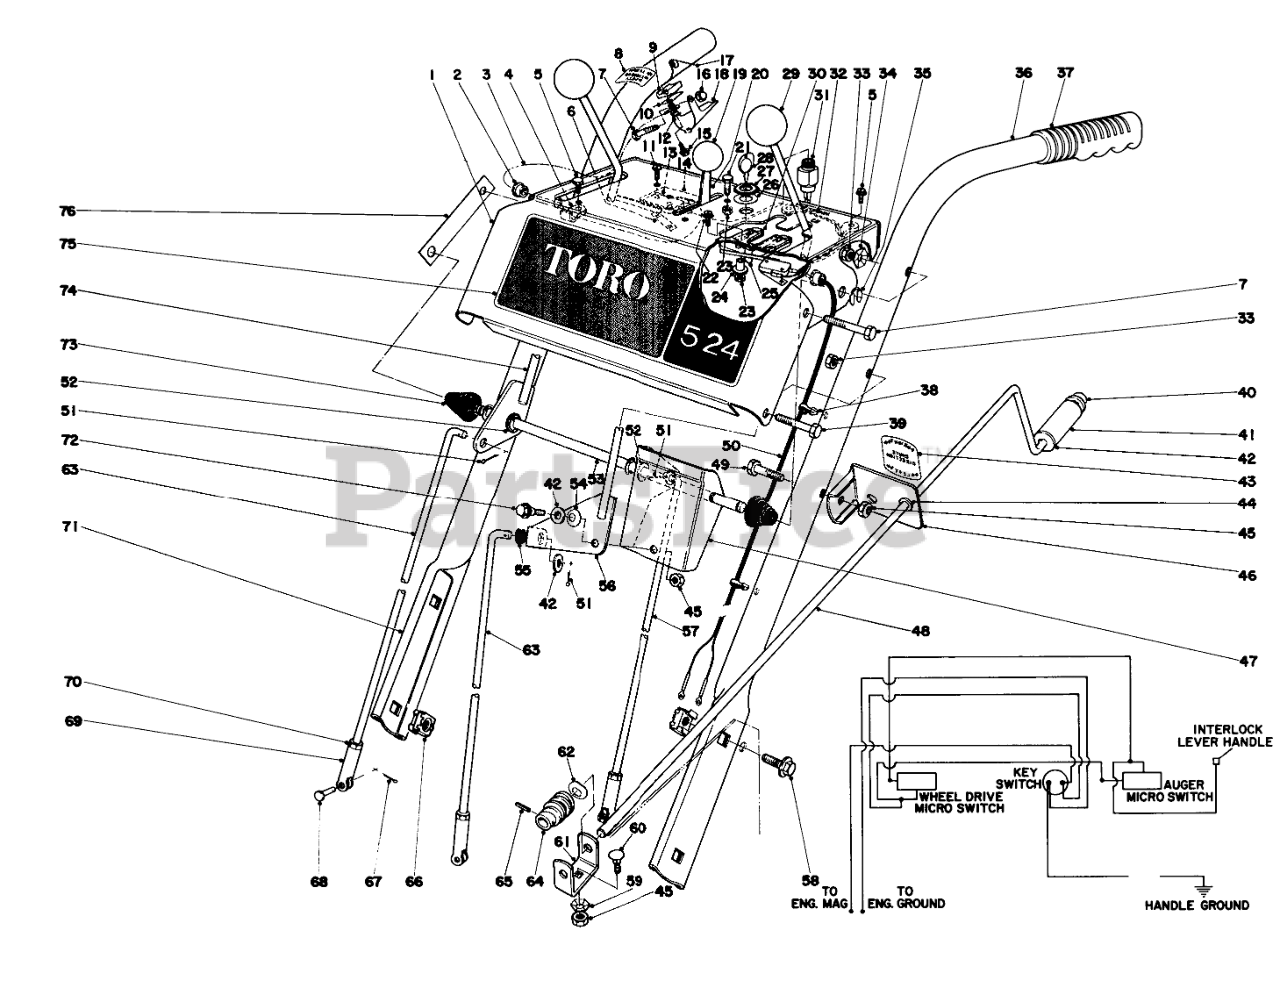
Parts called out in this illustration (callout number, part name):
1	Escutcheon
2	Snap Bushing
3	WIRE ASM
4	PLASTIC CLIP
5	SCREW-HWHTF
6	NUT-SPEED
7	SCREW-HH
8	Decal Safety Interlock
9	Insulator
10	INTERLOCK CONTACT
11	SCREW-HEAD, PAN
12	WASHER INSULATOR
13	MICRO SWITCH
14	SWITCH MTG PAD
15	Screw
16	NUT-CAP
17	INTERLOCK SPRING
18	Safety Lever
19	CONTROL KNOB
20	Throttle Control
21	HEX HEAD SEMS 10-24X1/2
22	SCREW-SRH
23	Nut
24	INTERLOCK SPACER
25	INTERLOCK SPRING
26	WASHER-TOOTH, INTERNAL
27	NUT-HH
28	Ket (set of 2)
30	Slide Interlock
31	Switch
32	Decal Instruction
33	NUT-LOCK, CONE
34	Washer
35	Klip Ring
36	LEFT HANDLE
37	Grip Handle
38	Mount-Wire
39	SCREW-HH
40	RETAINER-PUSH ON
41	CHUTE CONTROL GRIP
42	WASHER-FLAT
43	Decal Chute Direction
44	Bushing
45	NUT-LOCK, CONE
46	Chute Control Rod Mounting Bracket (Incl. Ref. 43-44)
47	SHIFT BRACKET
48	CHUTE CONTROL ROD
49	SCREW-HH
50	Wire Harness
51	PIN-COTTER
52	WASHER-FLAT
53	PIVOT ROD
54	7/16 SPRING WASHER
55	GROMMET-RUBBER
56	SHIFT LEVER WA
57	TRACTION CONTROL ROD
58	SCREW-HHF
59	WASHER-LOCK
60	BOLT-CARR
61	WORM BRACKET
62	WASHER-SPRING
63	SPEED SELECTOR ROD
64	GEAR-WORM, CHUTE
65	PIN-SPRING
66	Retained Nut
67	PIN-COTTER
68	PIN-CLEVIS
69	Clevis
70	NUT-HJ
71	RIGHT HANDLE
72	SHOULDER SCREW
73	CONICAL SPRING
74	LEVER WA
75	ESCUTCHEON DECAL
76	ESCUTCHEON SUPT STRAP
